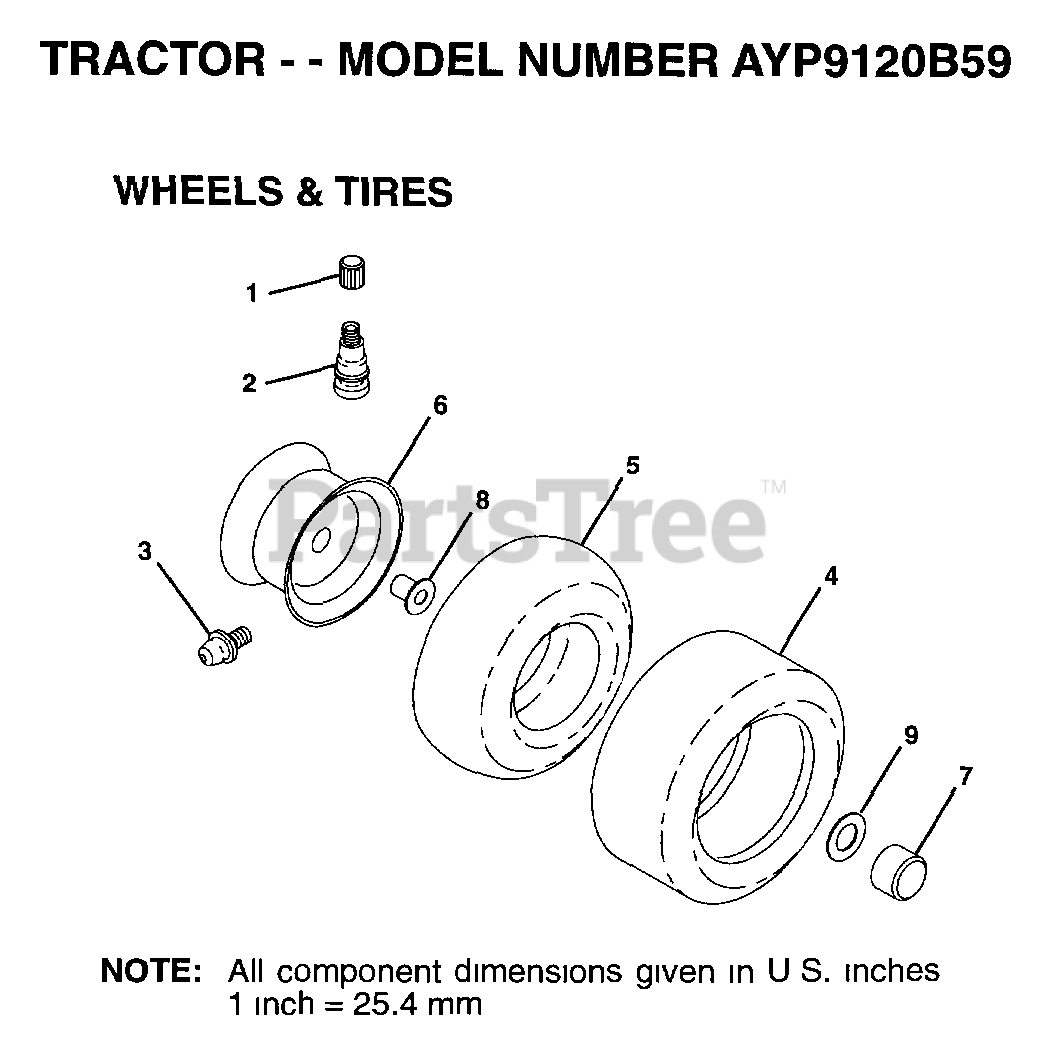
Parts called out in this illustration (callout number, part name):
1	VALVE CAP
2	VALVE STEM LT
3	FITTING LT
5	TUBE.5.3/4.5/6
7	HUB CAP
8	"FLANGE, BEARING"
9	WASHER
